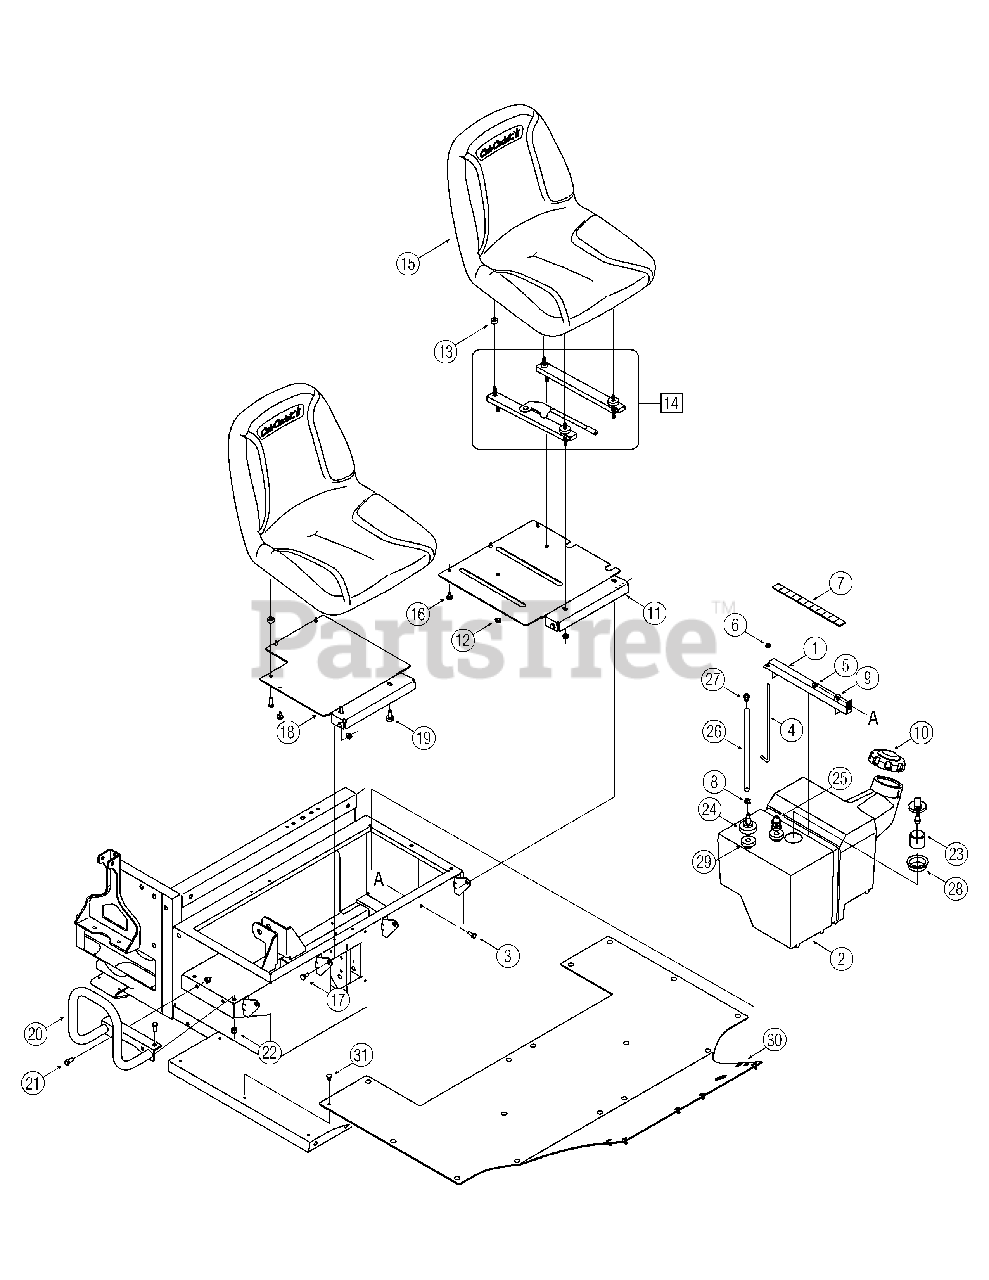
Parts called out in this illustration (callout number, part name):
1	Bracket Assembly, Fuel Tank
2	Tank Assembly, Fuel (Incl. valve, grommets, cap. switch & fitting)
2	Fuel Tank Only
3	Hex Screw, 5/16-18 x .75
4	Hold-down Rod, Fuel Tank
5	Sems Nut, 5/16-18
6	Nut, Flange Lock, 1/4-20
7	Gasket, Fuel Tank (11")
8	Clamp, Hose
9	Washer, .349 x .879 x .063
10	Cap, Fuel
11	Plate, Seat, LH
12	Nut, Flange Lock, 5/16-18, Gr5
13	Spacer, Seat
14	Track Assembly, Seat
15	Seat
16	Bumper
17	Shoulder Screw,.435 x.178-5/16 x.56
18	Plate, Seat, RH
19	Hex Screw, 5/16-18 x 1.0
22	Nut, Hex Lock Nylon, 3/8-16
23	Low Fuel Sensor
24	Fuel Return Fitting
25	Fuel Tank Shut Off Valve
26	Fuel Line Hose 20-inch
29	Fuel Tank Grommet
31	Retainer Clip
